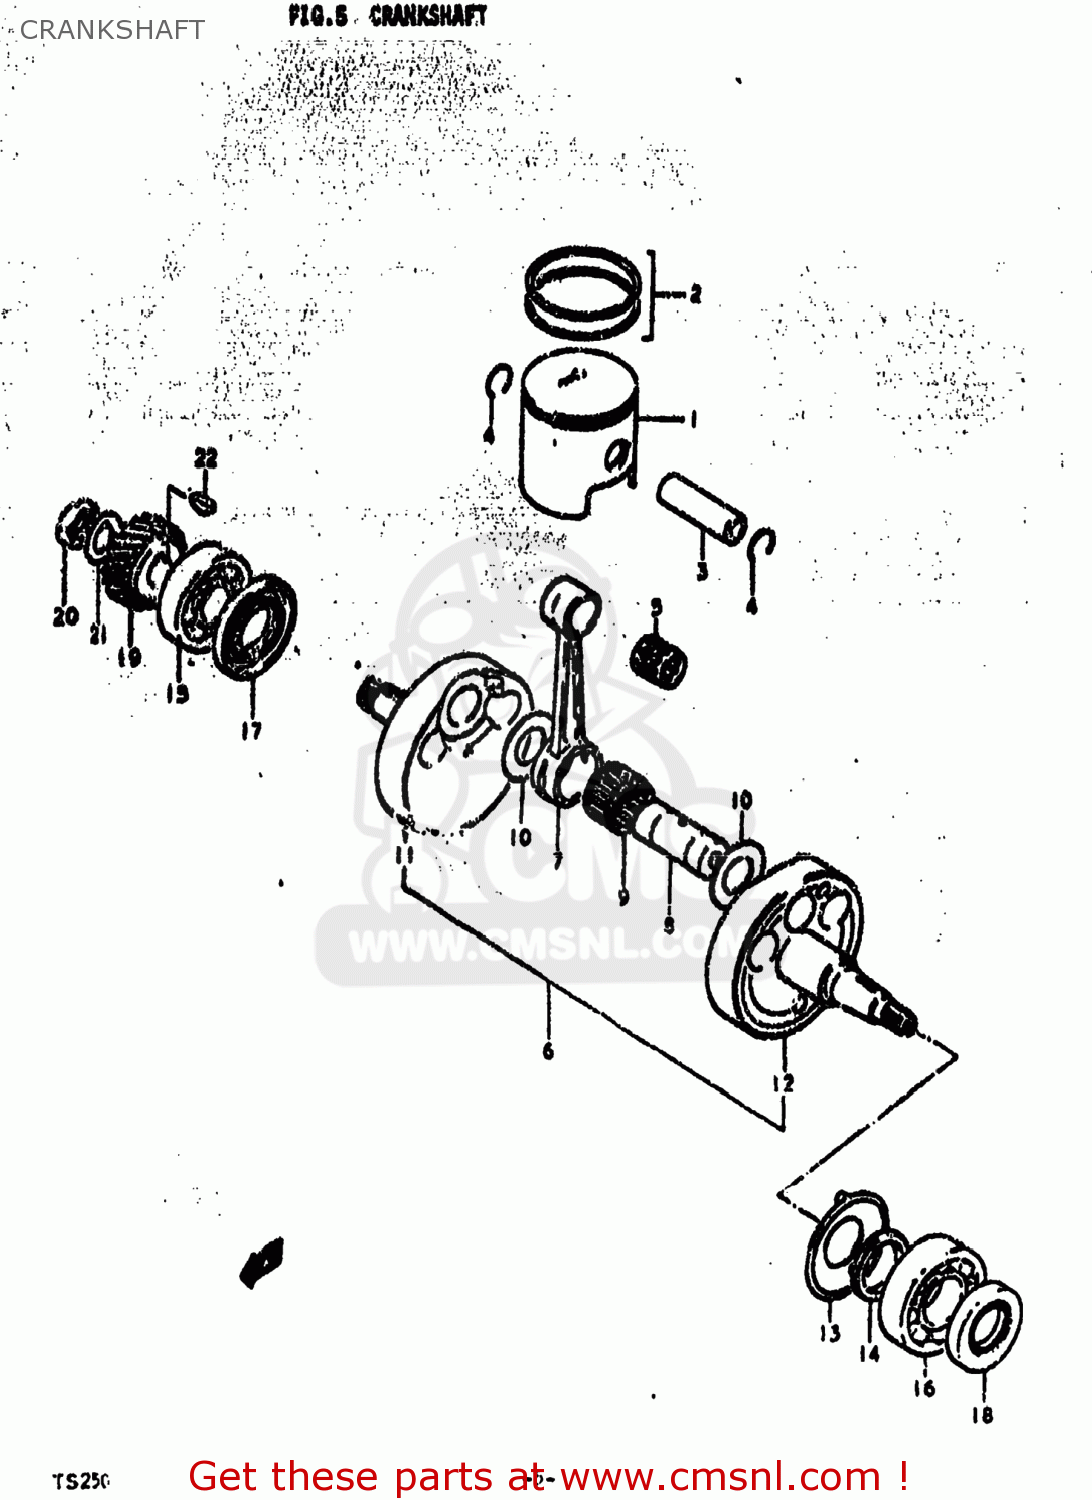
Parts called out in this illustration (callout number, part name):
1	PISTON
2	RING SET,PISTON
3	PIN,PISTON (18MM)
4	CIRCLIP
5	BEARING
6	CRANKSHAFT ASSEMBLY
7	ROD,CONNECTING
8	PIN,CRANK
9	BEARING(25X31X20)
10	WASHER
11	CRANKSHAFT
12	CRANKSHAFT,LEFT
13	PLATE,CRANKSHAFT OIL GUIDE
14	SPACER (30X45X4.8)
15	BEARING
16	BEARING(30X72X19)
17	SEAL,OIL(35X62X9)
18	OIL SEAL
19	GEAR,PRIMARY DRIVE
20	NUT
21	WASHER
22	KEY
